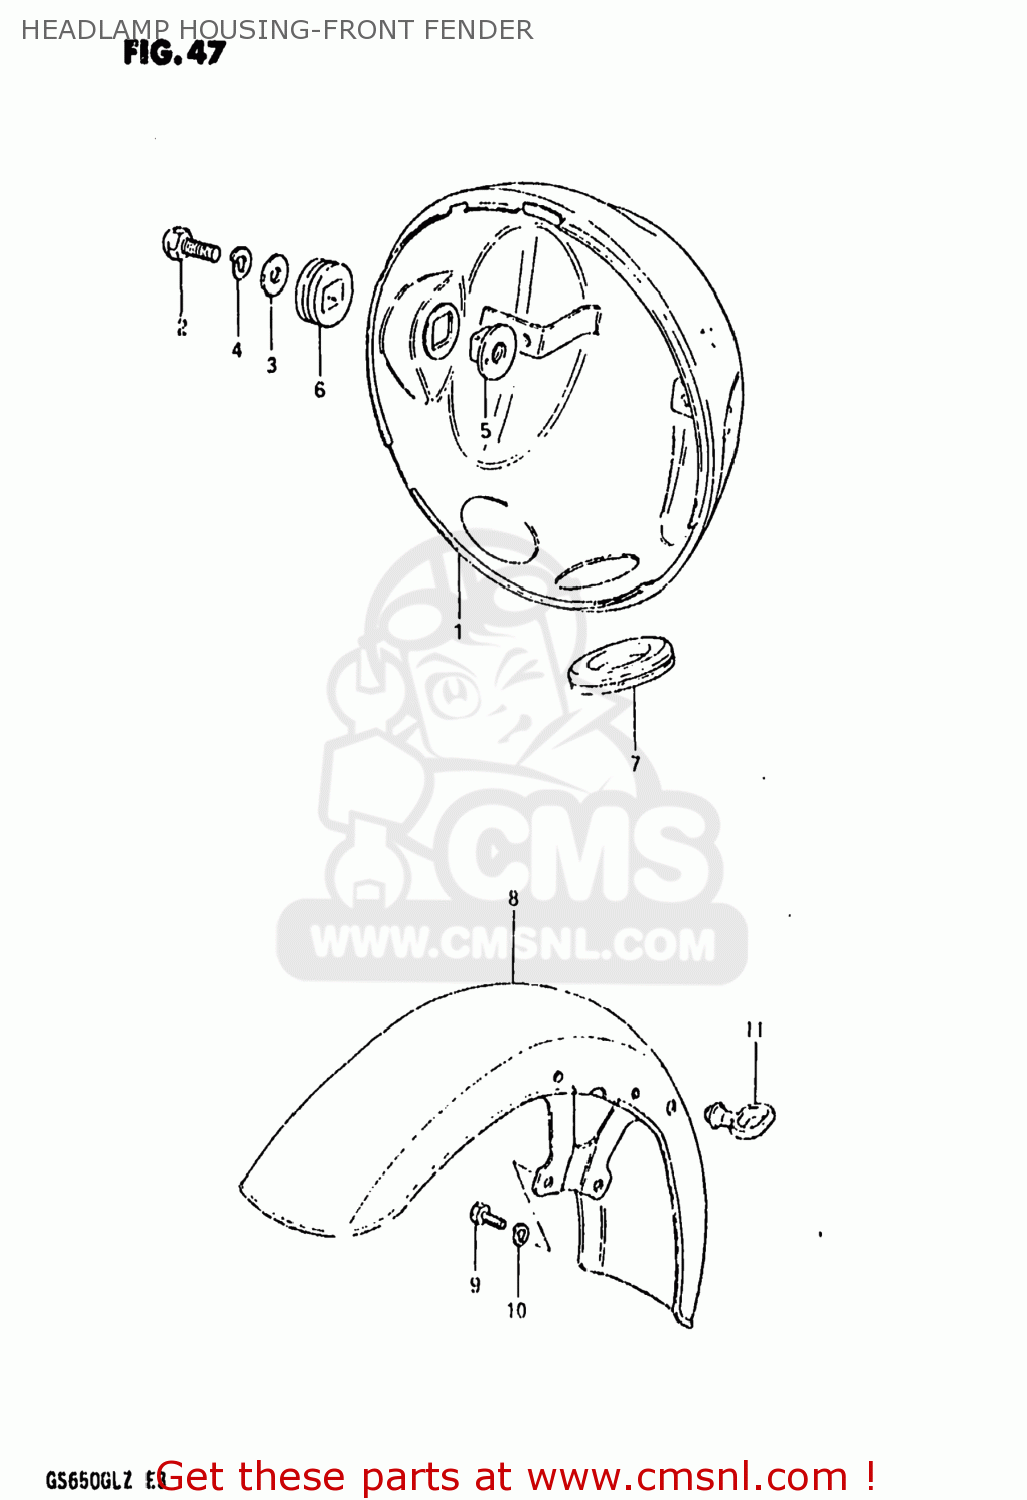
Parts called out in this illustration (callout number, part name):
1	HOUSING,HEADLAMP
2	BOLT
3	WASHER
4	LOCK WASHER
5	SPACER,HEADLAMP HOUSING
6	CUSHION,HEADLAMP HOUSING
7	GROMMET,HEADLAMP HOUSING
8	FENDER,FRONT
9	BOLT
10	LOCK WASHER
11	GUIDE,CABLE
